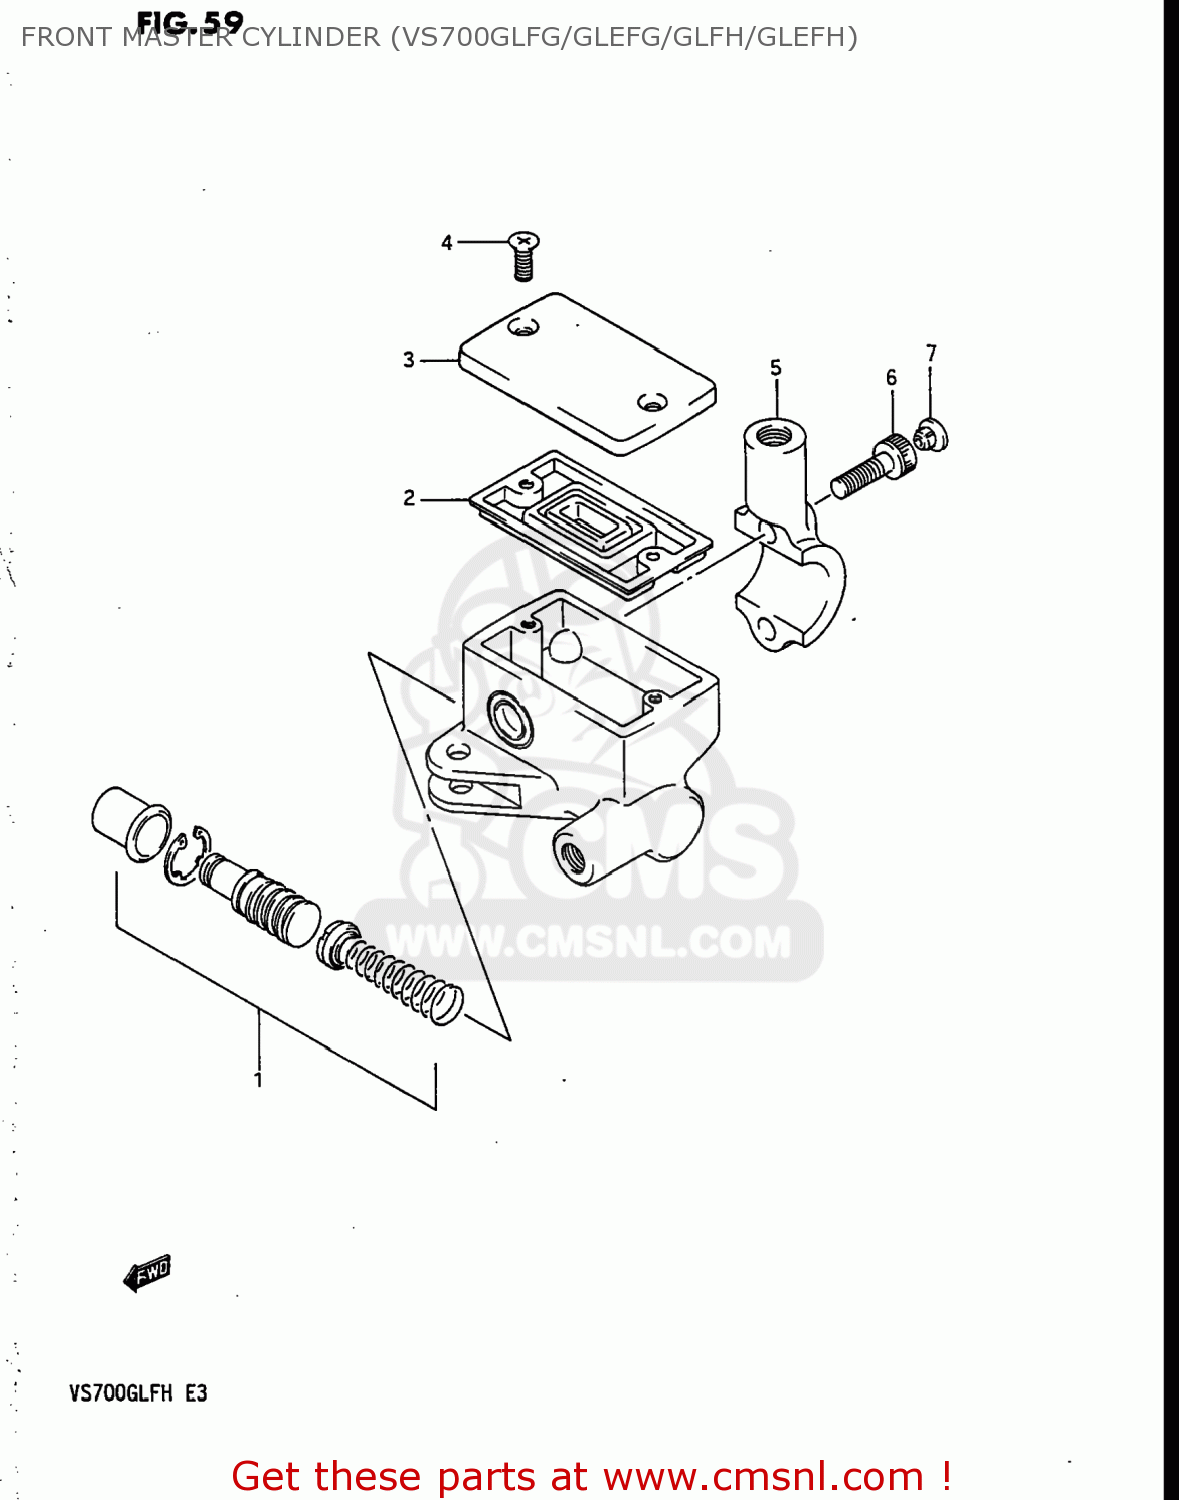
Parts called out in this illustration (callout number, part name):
1	PISTON & CUP SET
2	3
3	CAP
4	SCREW,RESERVOIR CAP
5	HOLDER
6	BOLT ,6X20
7	CAP(OD:10)
